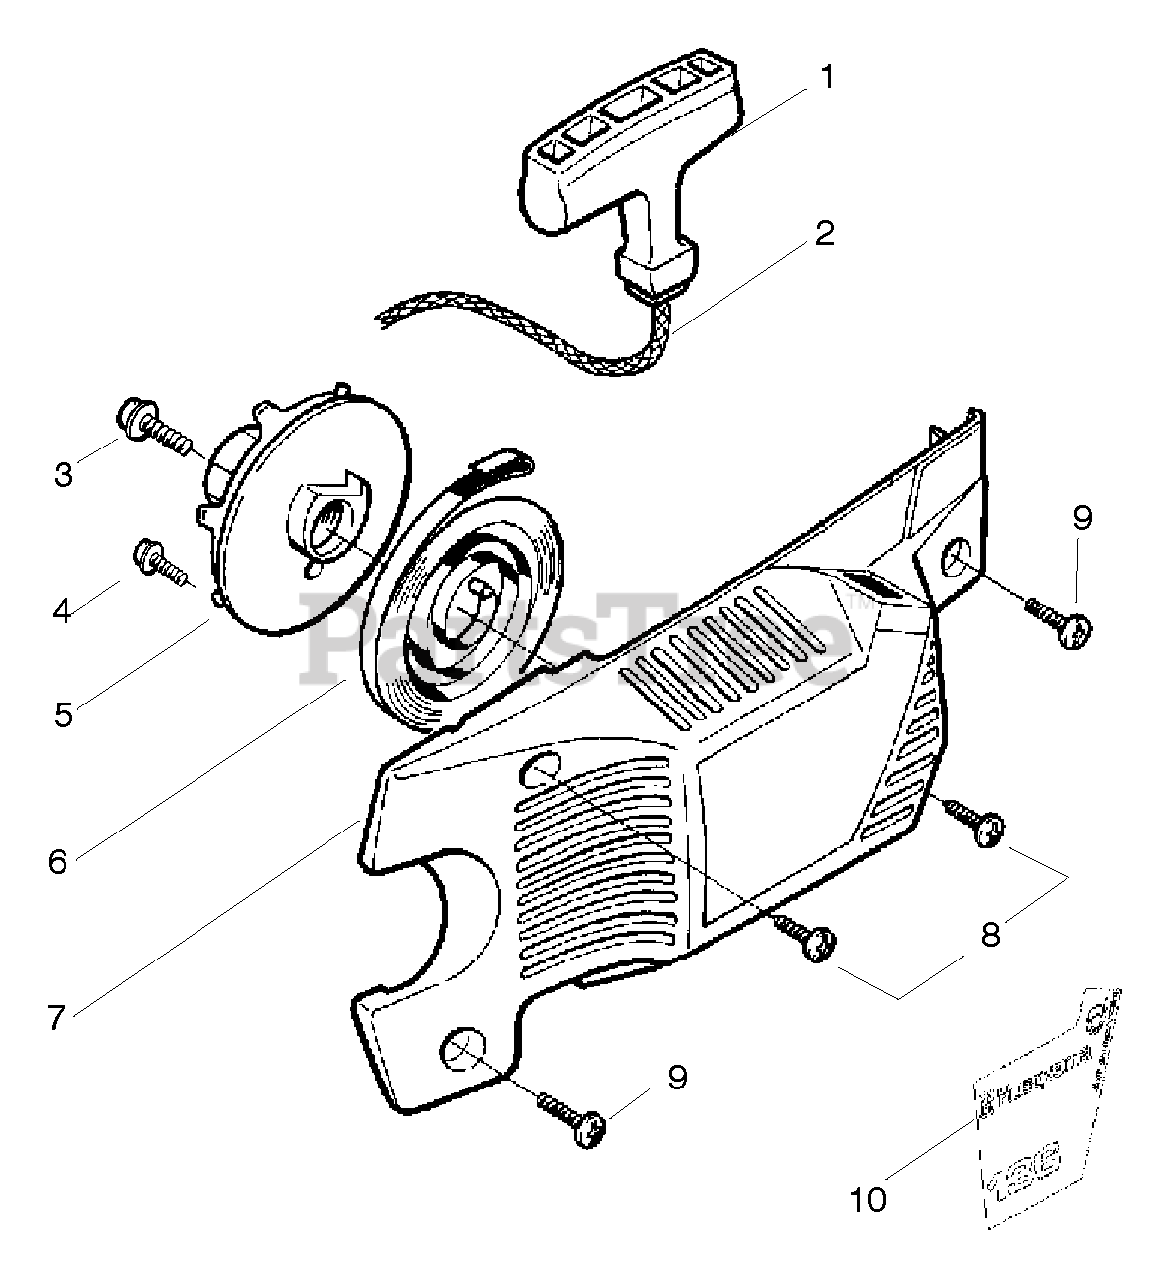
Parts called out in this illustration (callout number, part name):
1	Starter Handle
5	Starter-Pulley Kit
6	Recoil Spring
7	Fan Housing Assembly
10	Decal -Model 136
10	Decal -Model 141
